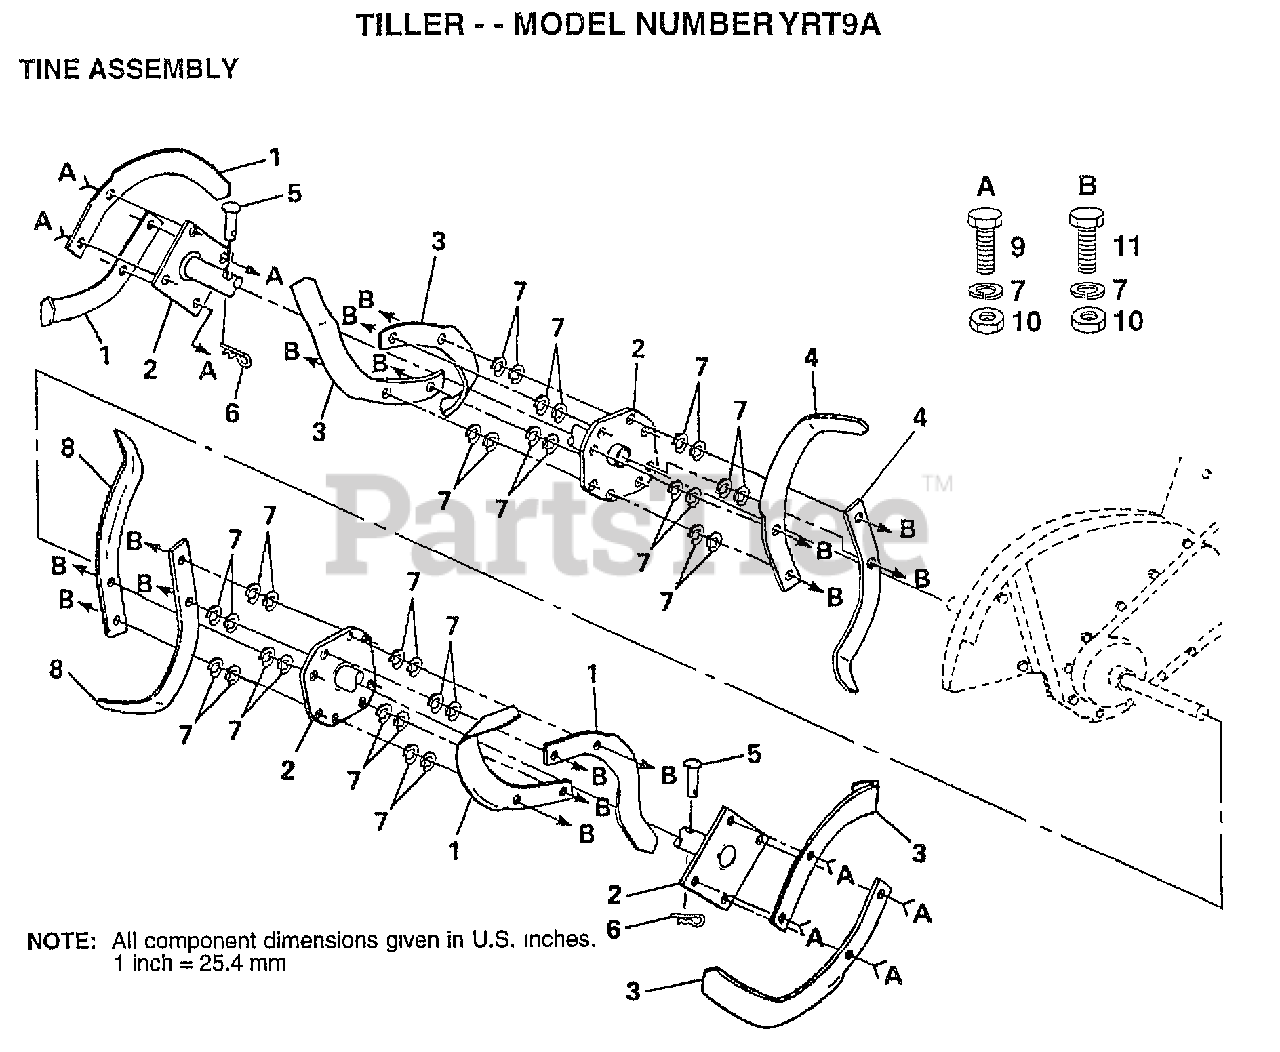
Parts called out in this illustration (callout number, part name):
2	TINE ASSY CRT
4	TINE.LH.CRT
5	RIVET.PAN HD.1.75
6	RETAINER.SPRING
7	LOCKWASHER
8	TINE RH CRT
9	BOLT
11	BOLT.3/8-24X1-1/2
